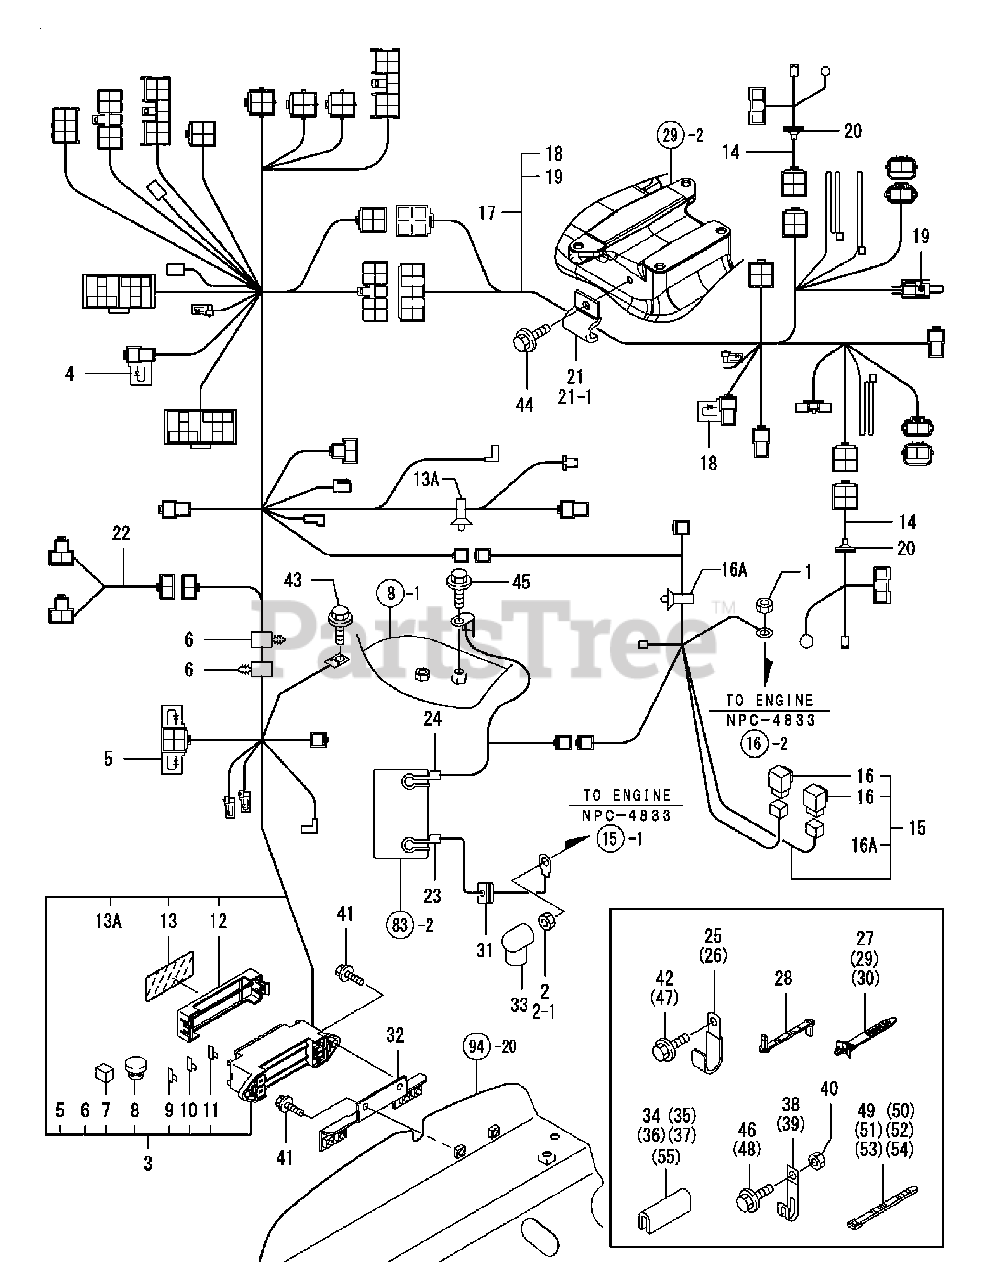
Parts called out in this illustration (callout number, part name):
1	NUT W/WASHER 6
2	NUT W/WASHER 8
2-1	NUT W/WASHER 8
3	WIRING HARNESS A CMP
12	COVER, FUSE BOX
14	HARNESS C ASSY.
15	WIRING HARNESS, START
16	FUSE, 80A SLOW BLOW
17	WIRING HARNESS B CMP
20	GROMMET, 25
21	CLAMP
21-1	CLAMP
22	WIRING HARNESS,
24	CABLE, BATTERY,NEG
25	CLAMP, WIRE HARNESS
26	CLAMP, WIRE HARNESS
31	GROMMET, CABLE
32	STAY, FUSE BOX
33	COVER, TERMINAL
34	COVER, HOSE PROTECTOR
35	COVER, HOSE PROTECTOR
36	COVER, HOSE PROTECTOR
37	COVER, HOSE PROTECTOR
38	CLAMP, BATTERY CABLE
39	CLAMP, WIRE HARNESS
40	NUT W/WASHER 8
41	BOLT M 6X 16 PLATED
42	BOLT M 8X 12 PLATED
43	BOLT M8X16, EARTH
44	BOLT M 8X 12 PLATED
45	BOLT M 8X 12 PLATED
46	BOLT M 8X 12 PLATED
47	BOLT M 8X 12 PLATED
48	BOLT M 8X 30 PLATED
